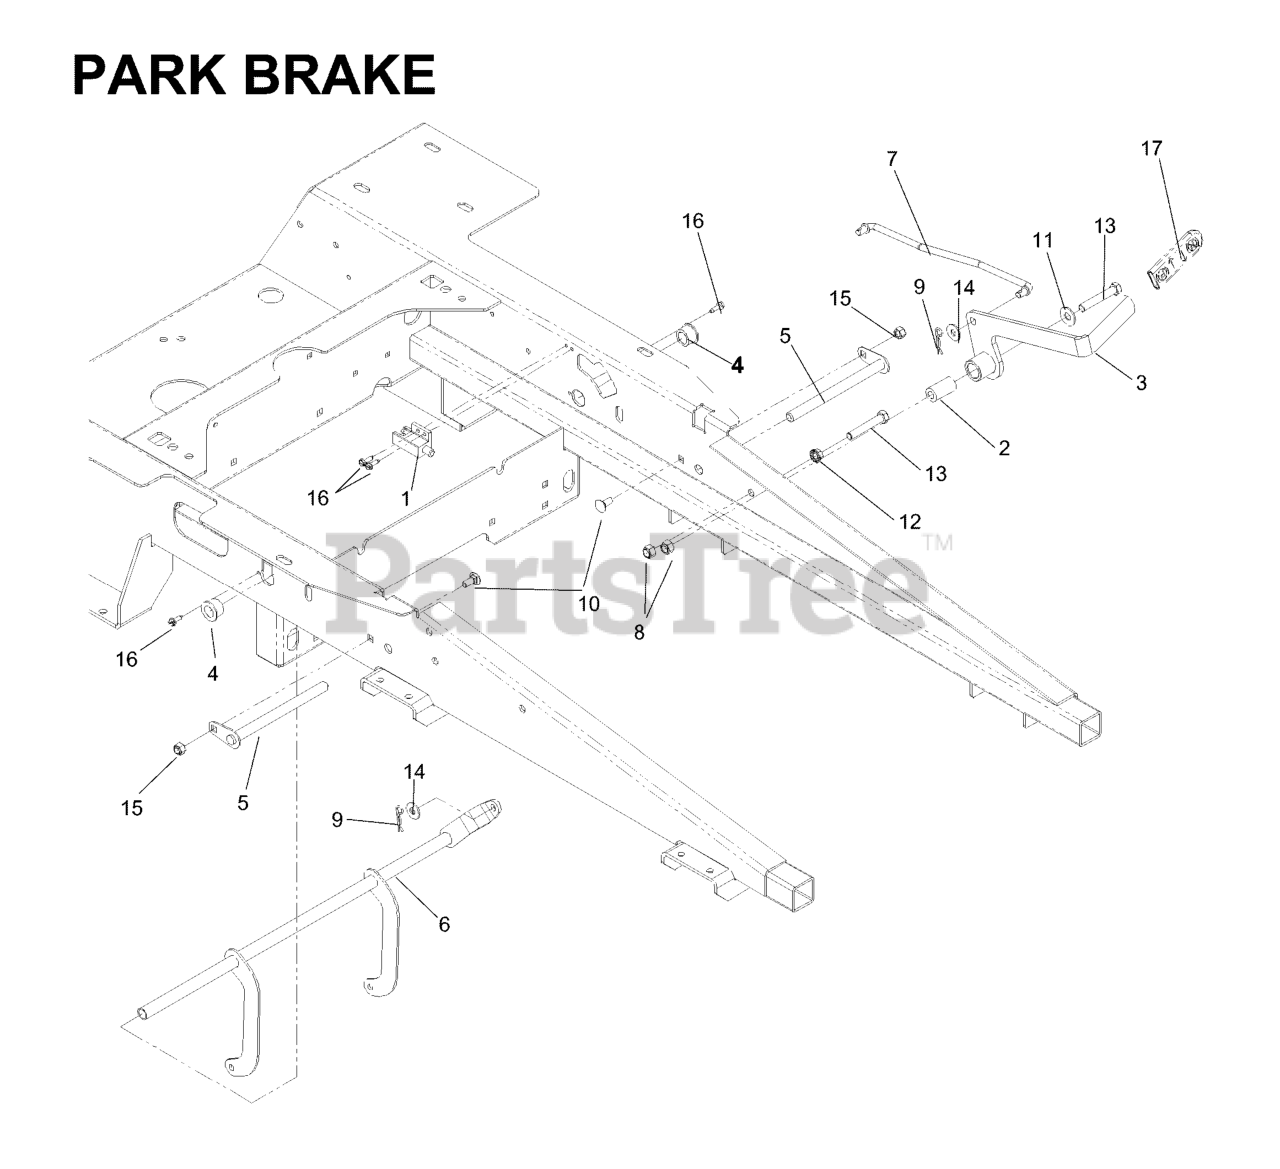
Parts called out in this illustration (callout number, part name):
1	SWITCH, INTERLOCK
2	BUSHING, SLEEVE
3	BRAKE LEVER WLDMT
4	PLASTIC BUSHING
5	PIVOT SHAFT
6	BRAKE SHAFT
7	BRAKE LINKAGE
8	NUT 3/8-16 NYLOC
9	HAIRPIN #2
10	BOLT 5/16C X 3/4" CARRIAGE
11	WASHER 3/8 FLAT
12	NUT 5/16C WHIZ
13	HCS 3/8C X 2 1/4
14	WASHER 5/16 FLAT
15	NUT 5/16 NYLOC
16	SCREW #10 X 1/2 SELF TAPPING
17	GRIP, PARK BRAKE
